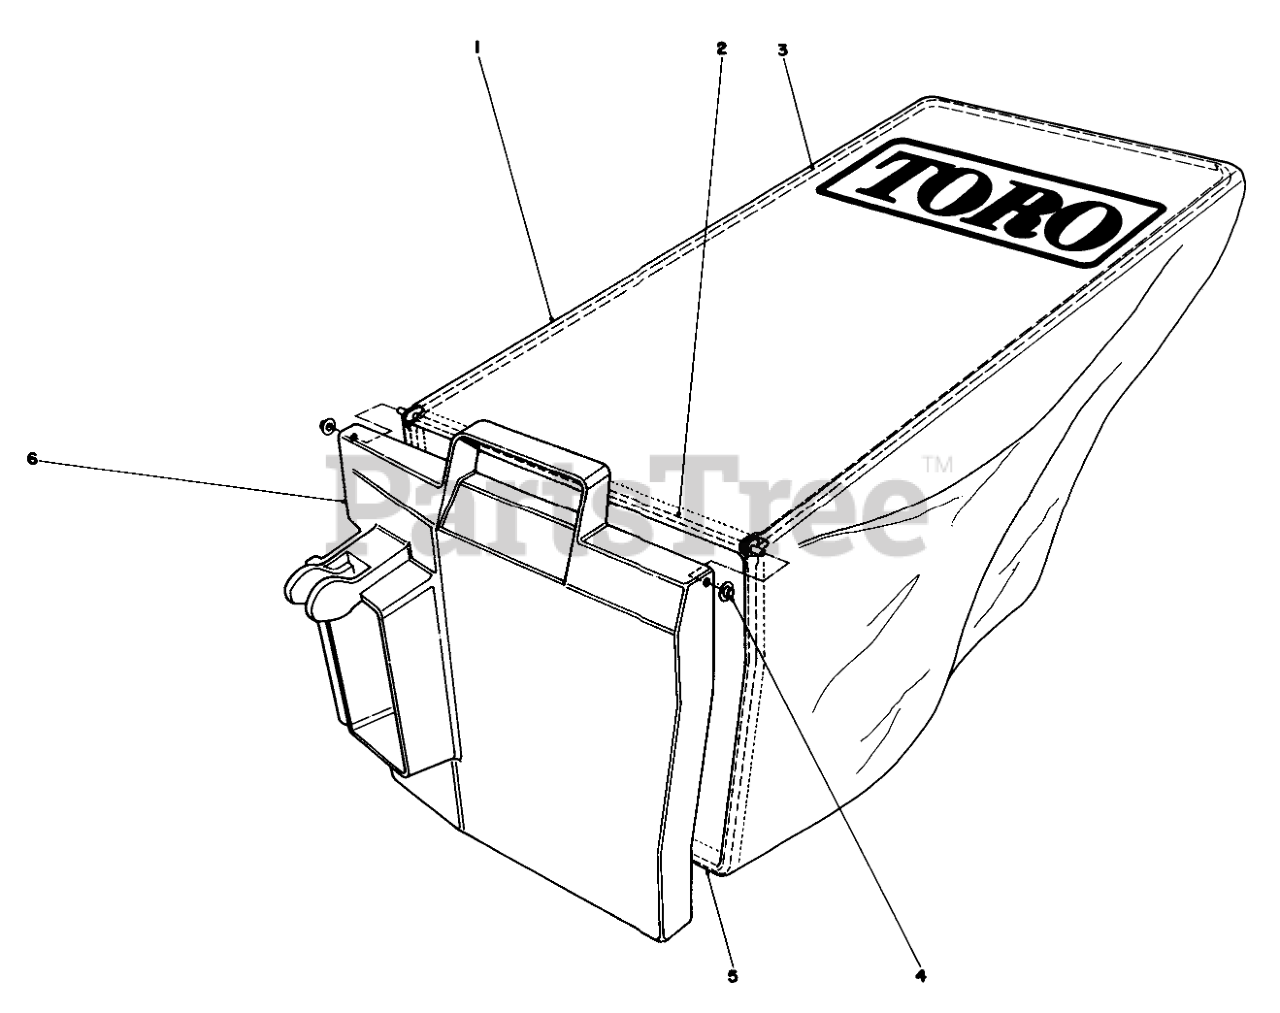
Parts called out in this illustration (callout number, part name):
1	18 BAGGER BAG 33-4552
2	HINGE PIN
3	BAG FRAME-UPPER
4	NUT-PUSH
5	Frame Bag
6	Door-Bag
